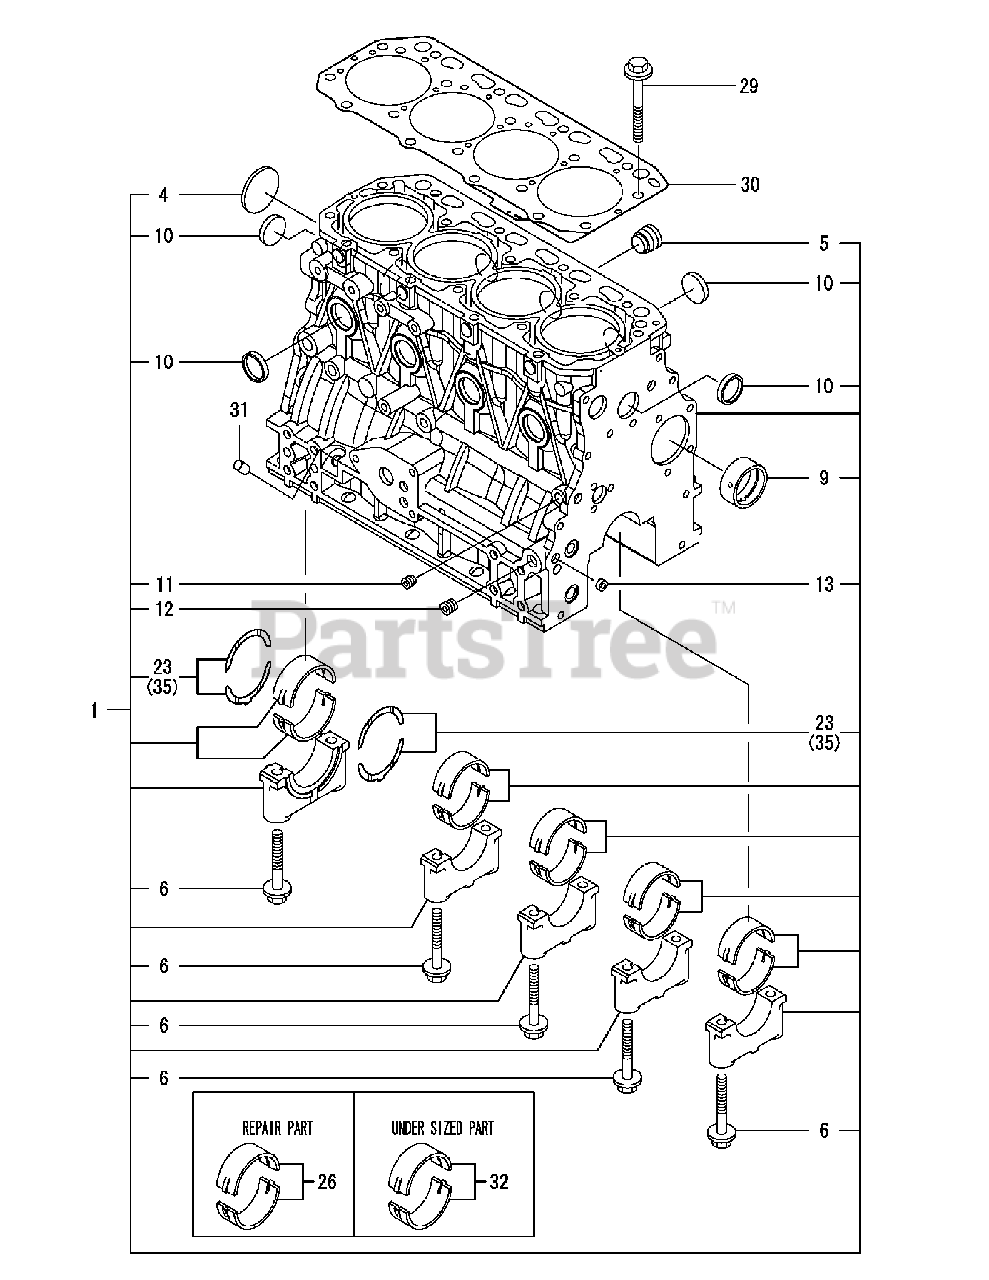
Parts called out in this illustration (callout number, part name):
1	BLOCK ASSY, CYLINDER
6	BOLT, METAL CAP
9	BUSH, CAMSHAFT A
10	PLUG 30
23	METAL ASSY, THRUST
26	MAIN BEARING SET
29	BOLT, CYLINDER HEAD
32	MAIN METAL US=0.25
35	BEARING, THRUST.25OS
